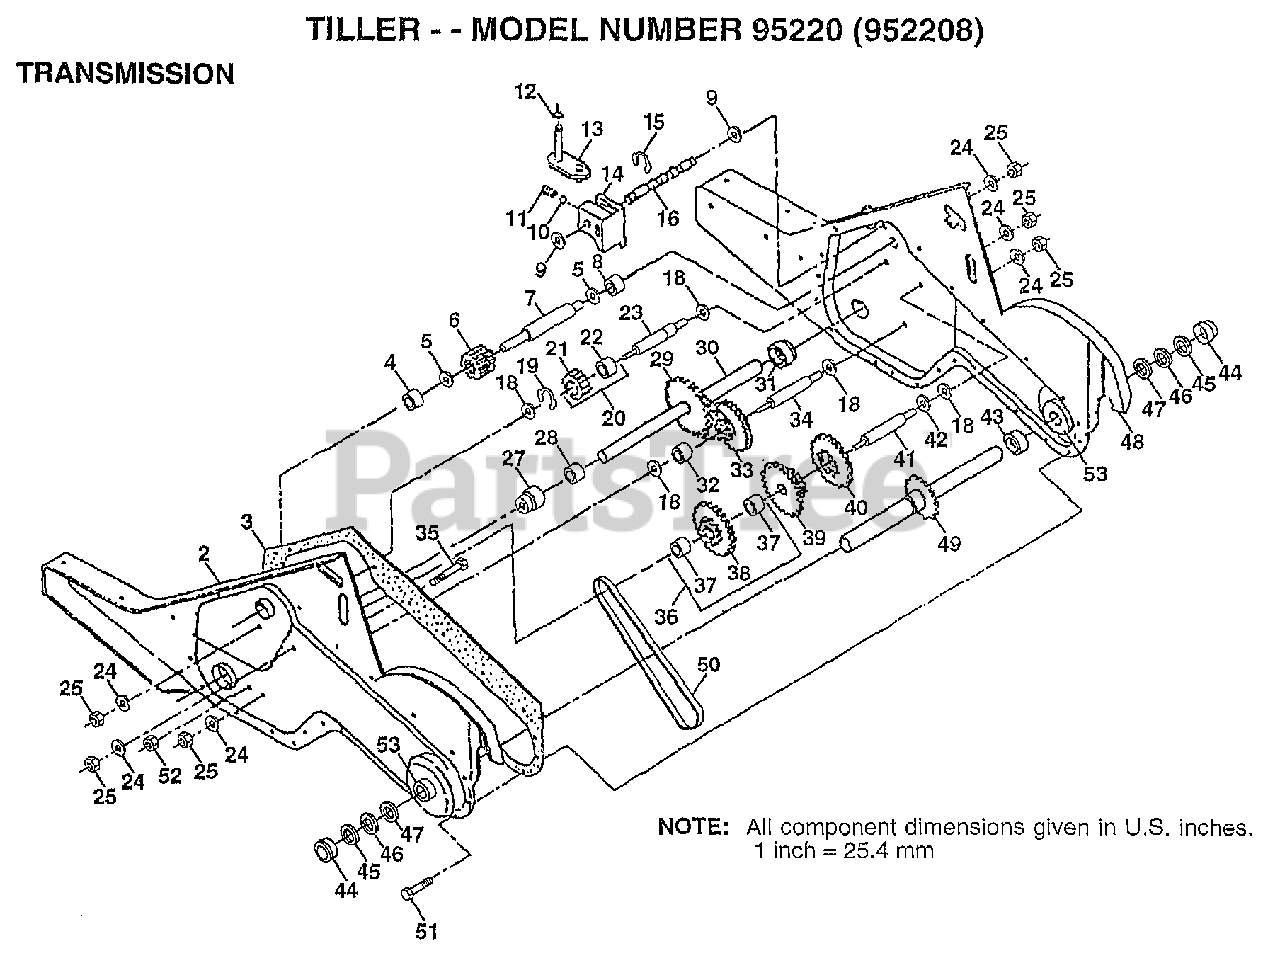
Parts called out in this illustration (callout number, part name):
2	GEARCASE LH W/BRG
3	GASKET TI
4	NEEDLE BRNG LT
5	"T, BEARING"
6	GEAR PINION INPUT
7	"SHAFT.INPUT.""D"""
8	"TI, BEARING"
9	WASHER SEAL
11	SPRING-SHIFT CRT
12	O-RING TI
13	BRACKET ASM SHIFT
14	SHIFT FORK TI
15	KLIP RING
16	SHAFT.SHIFTER
18	WASHER
19	KLIP RING
20	GEAR ASSY CRT
21	GEAR-REV IDLR CRT
22	NEEDLE BEARING TI
23	SHAFT CRT
24	LOCKWASHER
25	NUT.ASF.HEX.7/16
27	BEARING.SHAFT.LH.
28	BUSHING TI
29	CHAIN CRT
30	GROUND SHAFT ASSY
31	BEARING.SHAFT.RH.
32	SPACER TI
33	SPRCKT 8 GEAR CRT
34	SHFT 2ND RED. CRT
35	SCRW WHIZ LOK CRT
36	SPROCKET.ASM.W/BR
37	BEARING
39	GEAR TI
40	GEAR TI
41	REDUCTION SHFT TI
42	BRNG RACE
43	SPACER TI
44	CUP.FORMED.
45	RING SPIRAL CRT
46	SEAL RING RUBBER
47	OIL SEAL STD
48	GEARCASE RH W/BRG
49	TINE SHAFT
50	CHAIN.50 LINK TI
51	SCREW
52	NUT.HEX.5/16-18
